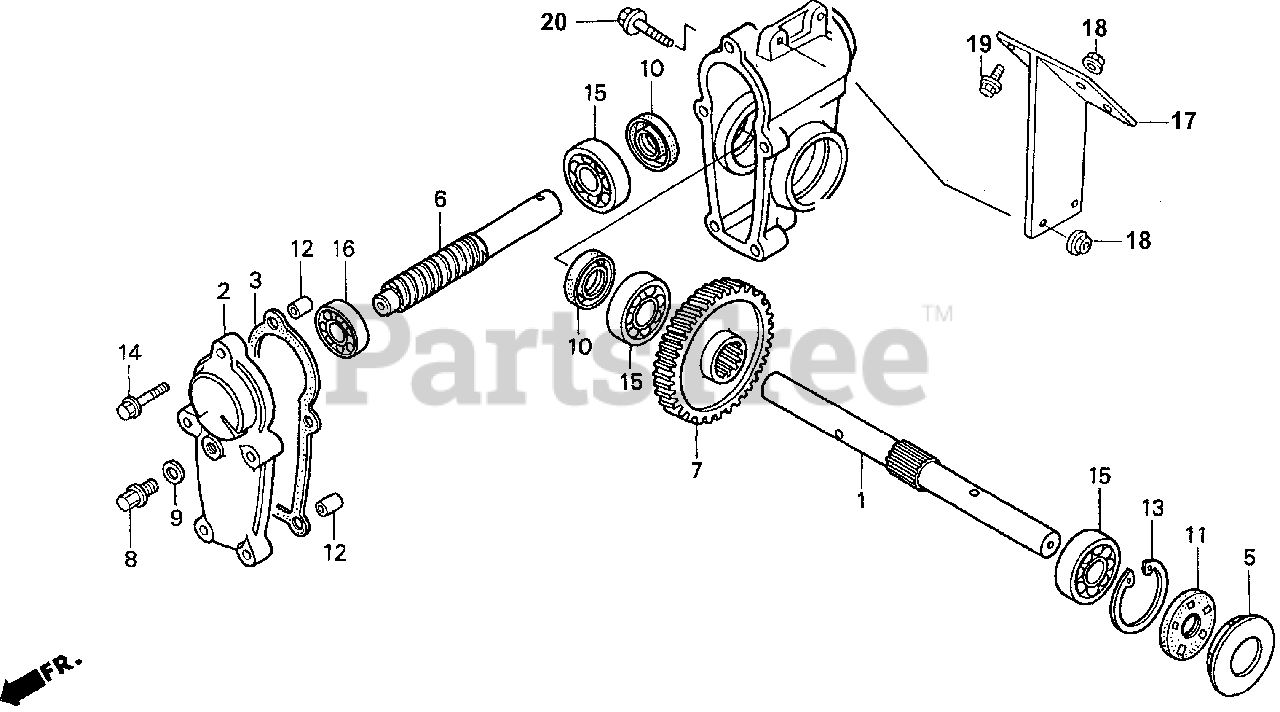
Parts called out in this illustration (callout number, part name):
1	SHAFT, AUGER
2	COVER, AUGER TRANSMISSION
3	GASKET, AUGER TRANSMISSION
4	CASE, AUGER TRANSMISSION
5	CAP, AUGER CASE
6	GEAR, DRIVE
7	GEAR, DRIVEN (55T)
8	BOLT, DRAIN PLUG
9	WASHER, DRAIN PLUG (10.2MM)
10	OIL SEAL (20X32X7)
11	OIL SEAL (20X42X8)
12	PIN, DOWEL (8X14)
13	CIRCLIP (INNER) (42MM)
14	BOLT, FLANGE (6X32)
15	BEARING, RADIAL BALL (6004)
16	BEARING, RADIAL BALL (6202)
17	BRACKET, AUGER HOUSING
18	NUT, FLANGE (8MM)
19	BOLT, FLANGE (8X14)
20	BOLT, FLANGE (8X25)
